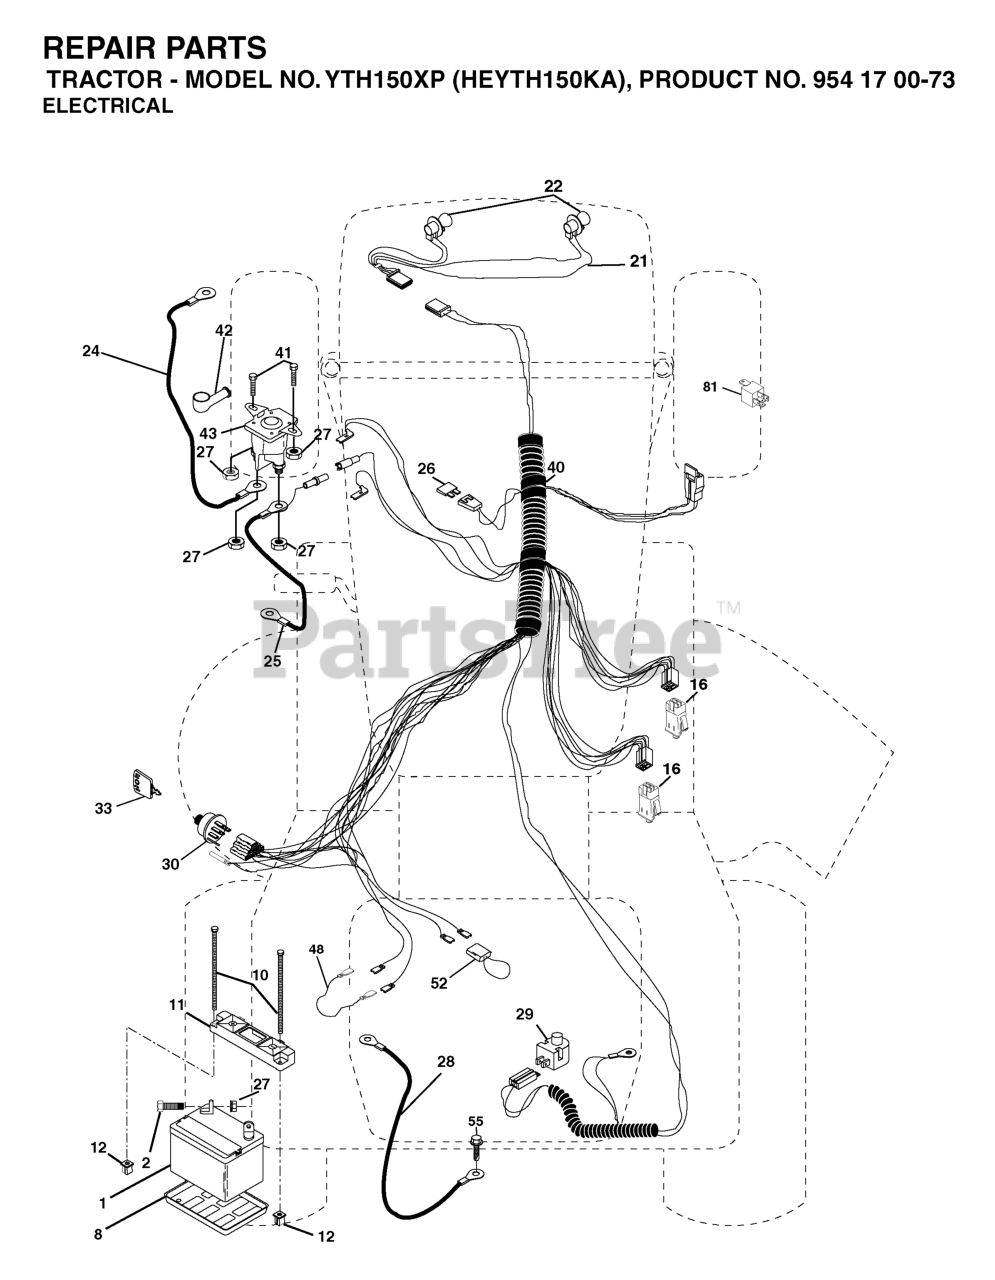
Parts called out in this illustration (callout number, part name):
1	Battery 12 Volt 25 Amp
2	BOLT.HEX.1/4.X.3/4.DICHROMATE
8	BATTERY TRAY T
10	BOLT 1/4-20 X 7.5
11	BATTERY HOLDDOWN FRONT MOUNT
12	NUT, PUSH NYLON 1/4" BATTERY
16	SWITCH INTERLOOK PUSH-IN
21	HARNESS.W/LIGHT SOCKET
24	BATTERY CABLE GT
25	CABLE BATTERY 6 GA 22" W/16W
26	FUSE 20AMP
27	NUT
28	CABLE GROUND 6 GA 21" 90T BLK
29	RP.SWITCH.PLUNGER.NC.GRAY
30	IGNITION SWITCH
33	KEY MLD GEN DELTA
40	HARNESS.IGNITION
41	BOLT
42	TERMINAL COVER
43	SOLENOID
48	ADAPTER.AMMETER
52	WIRE PROTECTION LOOP
55	Screw 5/16-18 x 1/2 Hex, Self Tapping 5/16-18 x 1/2
81	RELAY.ASSY.T
